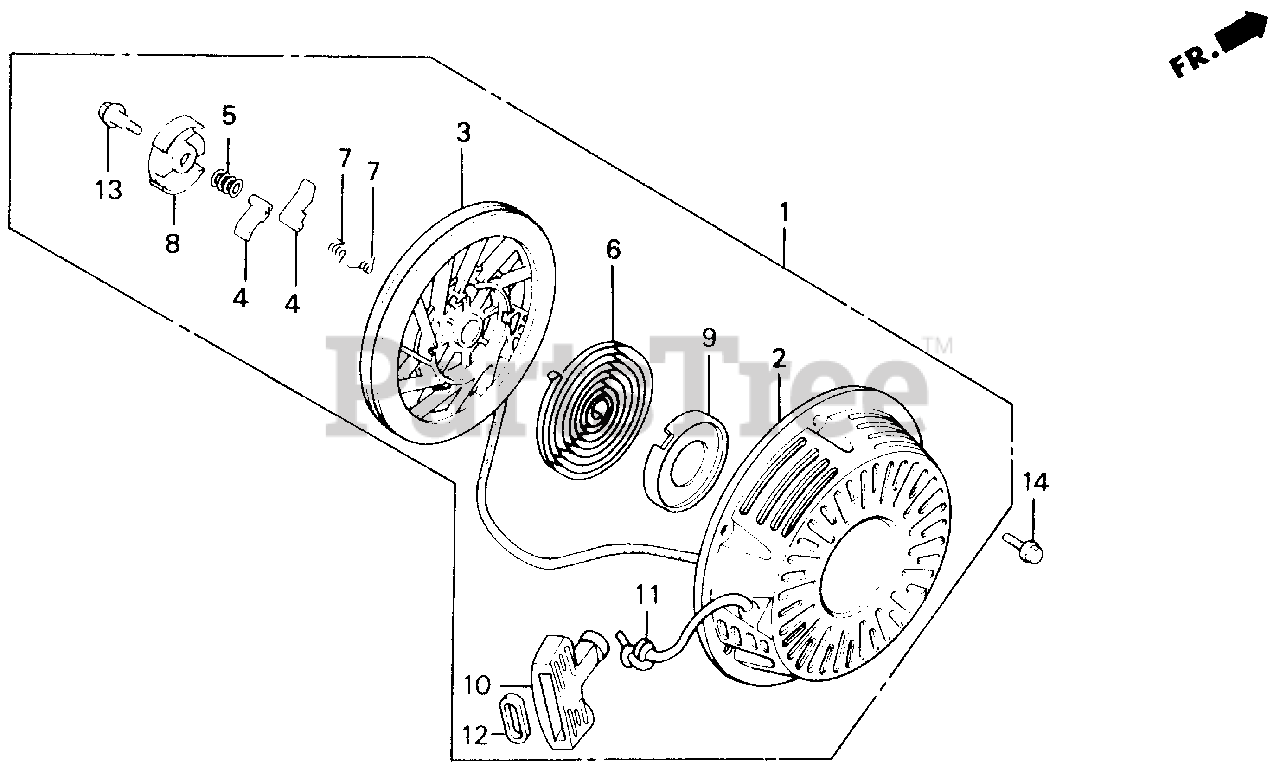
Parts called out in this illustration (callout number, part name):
1	STARTER ASSY., RECOIL *R8* (BRIGHT RED)
1	STARTER ASSY., RECOIL *NH1* (BLACK)
1	STARTER ASSY., RECOIL *R280* (POWER RED)
2	CASE, RECOIL STARTER *R8* (BRIGHT RED)
2	CASE, RECOIL STARTER *NH1* (BLACK)
3	PULLEY, RECOIL STARTER
4	RATCHET, STARTER
5	SPRING, FRICTION
6	SPRING, STARTER RETURN
7	SPRING, RATCHET
8	RETAINER, SPRING
10	GRIP, STARTER
11	ROPE, RECOIL STARTER
12	GRIP, REINFORCEMENT
13	SCREW, CENTER
14	BOLT, FLANGE (6X8)
